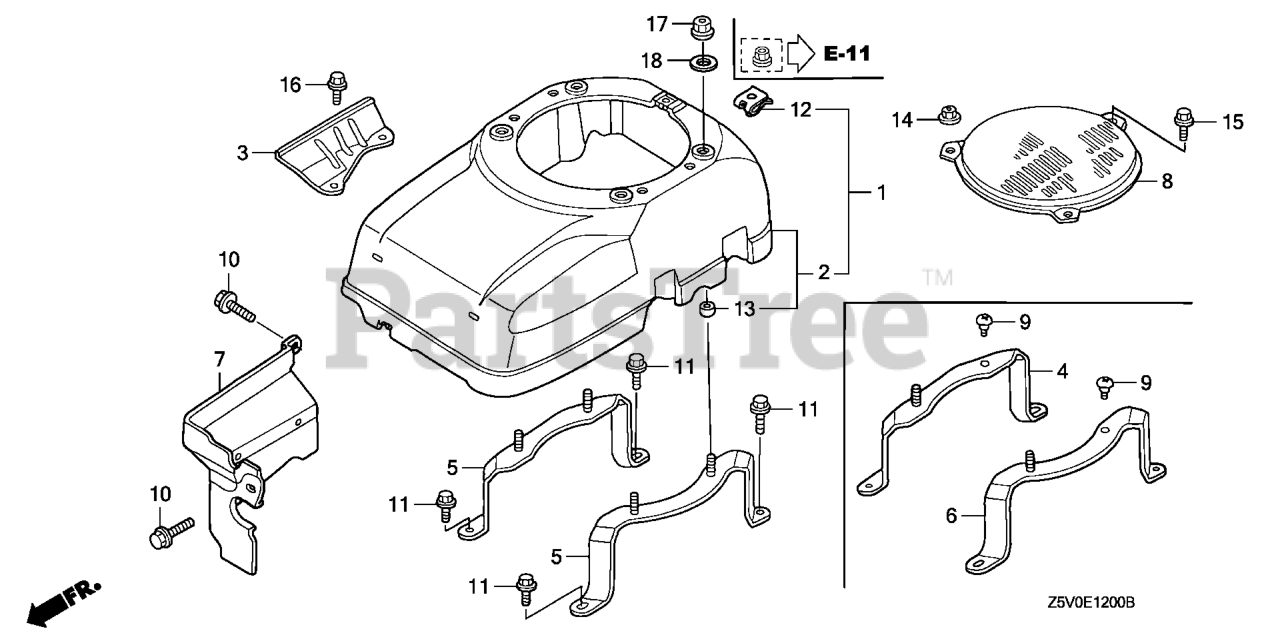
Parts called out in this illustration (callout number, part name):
2	COVER, FAN *NH1* (BLACK)
2	COVER, FAN *R280* (POWER RED)
3	PLATE, SIDE
5	BRACKET, FAN COVER
11	BOLT, FLANGE (6X16)
13	COLLAR, FAN COVER
16	BOLT, FLANGE (8X20)
